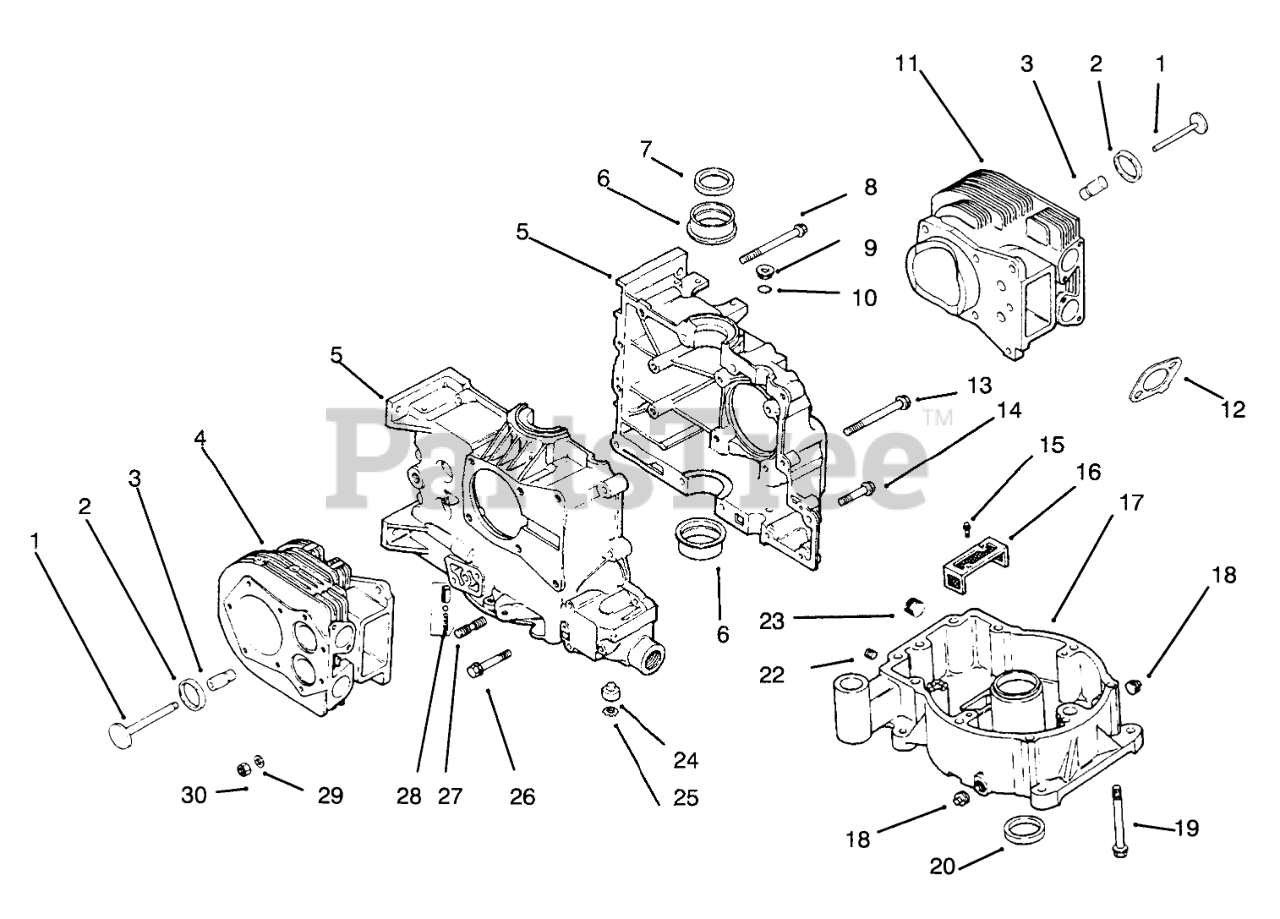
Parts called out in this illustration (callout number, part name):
1	Valve-Exhaust (Ref)
2	Inset-Valve Seat
3	Guide-Valve
4	Kit-#2 Cylinder Barrel(Incl. Ref. #1-3)
5	Crankcase (Ref. Short Block)
6	Bearing-Sleeve
7	Seal-Rear Oil
8	Screw-Hex Flange
9	Plug
10	O-Ring
11	Kit-#2 Cylinder Barrel(Incl. Ref. #1-3)
12	Gasket-Exhaust
13	Screw-Hex. Flange
14	Screw-Hex. Flange
15	Screw
16	Filter-Oil Pickup
17	Pan-Oil
18	Plug
19	Screw-Hex. Washer Hd.
20	Seal-Rear Oil
22	Plug-Hex Countersunk
23	Plug
24	Shaft-Governor
25	Ring-Retaining
26	Screw-Hex Flange
27	Stud-Step
28	Kit-Oil Relief
29	Washer-Flat
30	Nut
